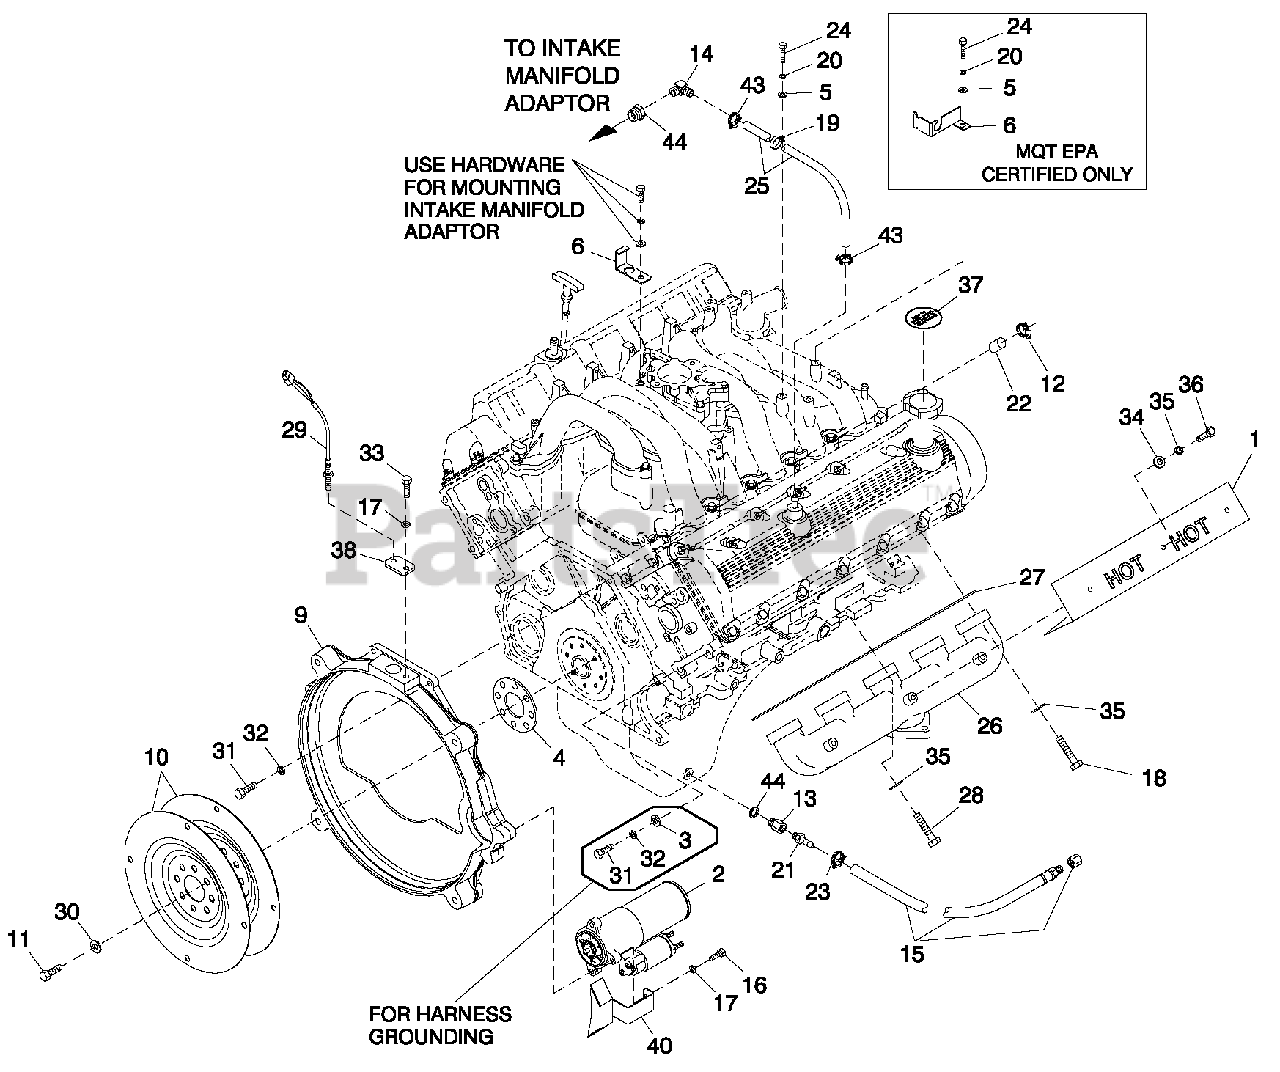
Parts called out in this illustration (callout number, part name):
1	HEAT SHIELD EXHAUST
2	STARTER MOTOR FORD V-10 ENGINE
3	WASHER FLAT3/8-M10ZINC
4	SPACER FLEXPLATE5.4L/6.8L(1800 RPMUNITS ONLY)
5	WASHER FLAT 1/4-M6ZINC
6	BRACKET SIGNAL CONDITIONER
7	TIE WRAP UL7.4" X .19" BLK (NOTSHOWN)
8	WASHER NYLON .565
9	ENGINE ADA PTER54L/6.8L
10	FLEXPLATE 2 POLE (1800 RPM UNITS ONLY)
11	SCREW HHCM10-1.0X 25 G10.9
12	CLAM PHOSE #10.56 -1.06 (1800 RPM UNITSONLY)
13	ADAPTERM14-1.50 X 3/8N P T
14	BARBED EL 90 3/8NPTX5/8
15	HOSE DRAIN ASSY 28"
16	SCREW HHCM8-1.25X 30 G8.8
17	WASHER LOCK M8-5/16
18	SCREW SHC M 8-1.25X 35S S
19	CLAMP VINYL .7 5X .3 4 3 Z
20	WASHER LOCK M6-1/4
21	BARBED STR 3 /8N P T X 3 /8
22	CAP HOSE (1800 R PM UNITS ONLY)
23	CLAM PHOSE .38-.87
24	SCREWHHCM6-1.0 X 1 6G 8 .8
25	HOSE COOL 5/8" ID 250#W P (14" )
26	EXH MAN FOLD MACH 6.8L V-10
27	GASKET EXHAUST MANIFOLD
28	SCREW HHCM8-1.25X 35 S SG8.8
29	ASSY MAGPICK U P (3/8-24 MALE)
30	WASHER F LA T .43 X1.00
31	SCREW SHC M10-1.5X 25 G12.9
32	WASHER LOCK M10
33	SCREW HHCM8-1.25X 20 G8.8
34	WASHER FLATM8 SS
35	WASHER LOCK M8SSTL
36	SCREW HHC 91 6 -1 8X 1/2 SSTL
37	DECAL REFER TO OWNERS MANUAL
38	PLATE MAGPICK-UPADAPTOR
40	COVER STARTER 5l4 & 6.8 FORD CPL
43	CLAM PHOSE #10.56-1.06
44	ADAPTOR 1/4' NPT TO 3/8" NPT
